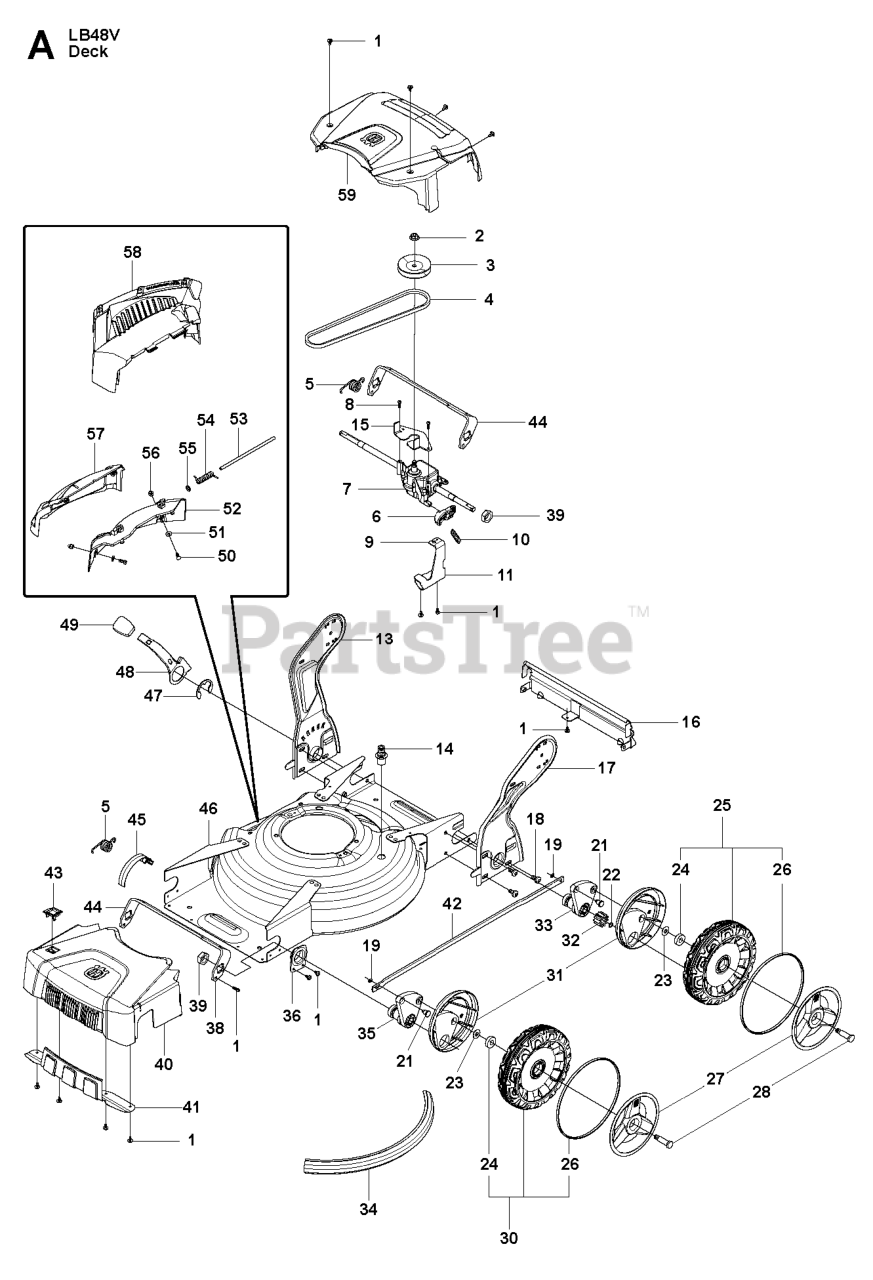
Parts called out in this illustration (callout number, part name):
1	SCREW ITXPANTT M5X10 ZPB (A00
4	BELT WRAPPED V-BELT Z 29.5
8	SCREW ITXPANT T50X16 ZN/FE (A
19	FASTENER
24	BALL BEARING
46	CHASSIS 48S A009 PAINTED
59	REAR COVER A009-2
